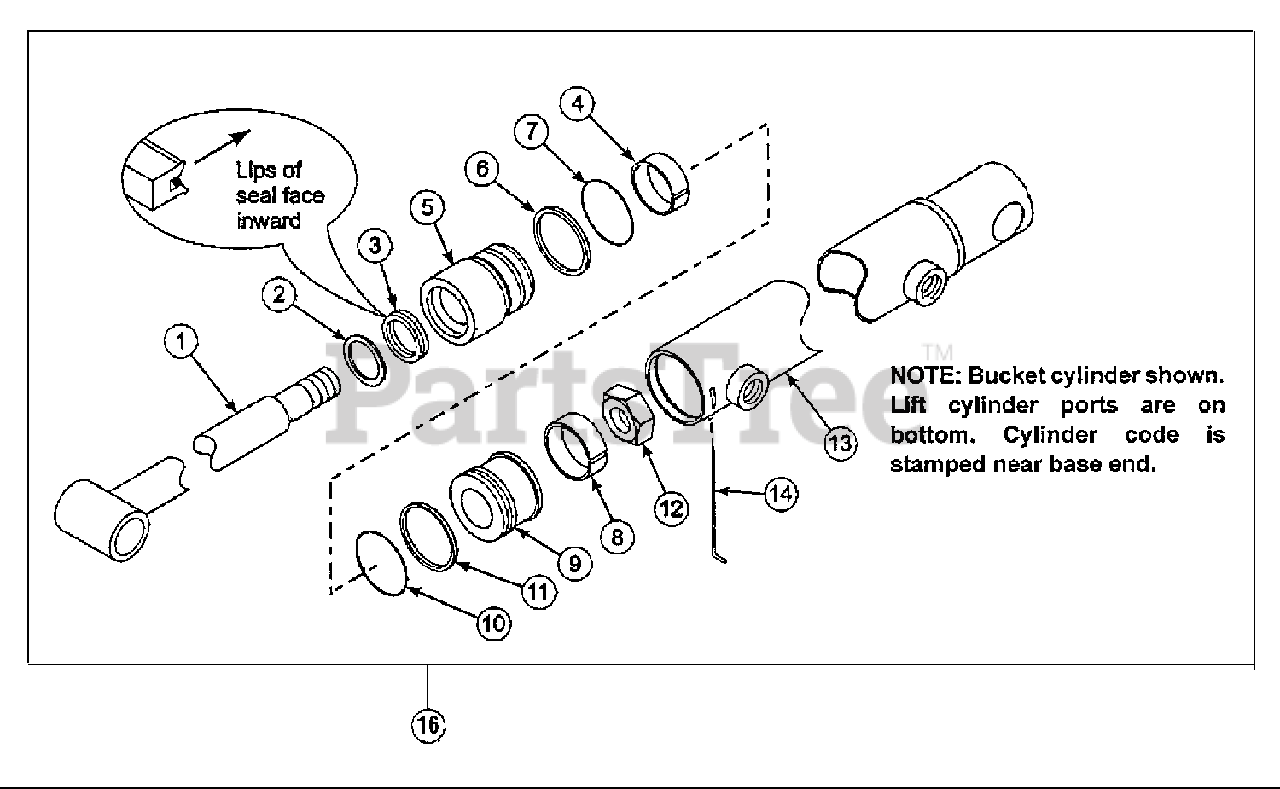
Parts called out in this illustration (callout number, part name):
1	ROD, Cylinder, 1"
5	HEAD, Cylinder
12	NUT, Hex Lock, 3/4-10
13	TUBE, Cylinder
15	REPAIR KIT, (Contains Ref. Nos. 2-4, 6-8, 10, 11 & 14)
16	CYLINDER LIFT, Complete
